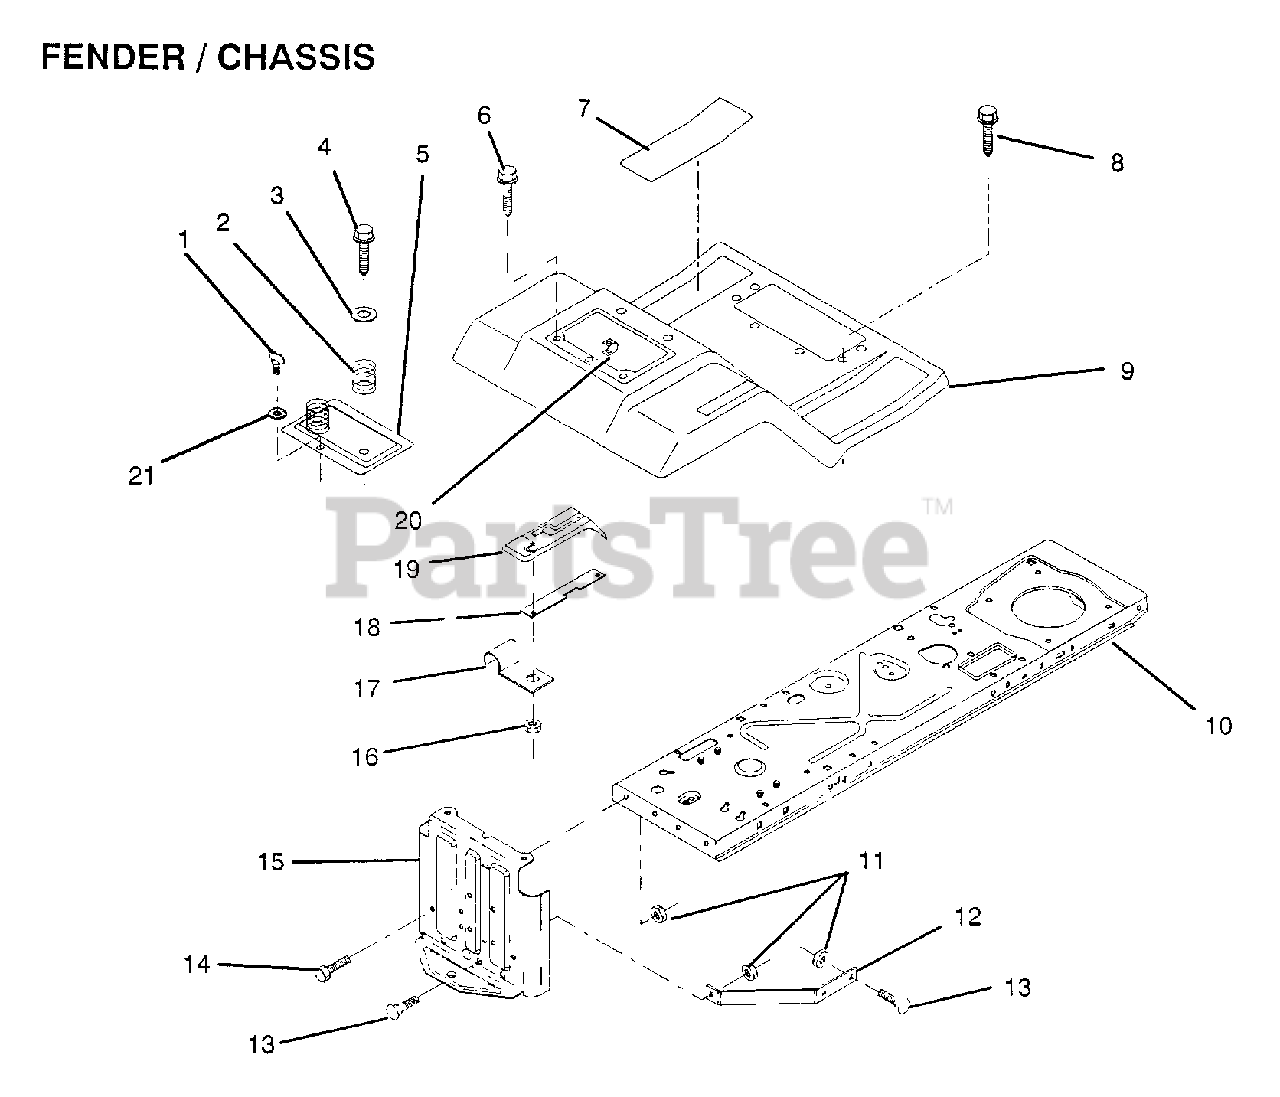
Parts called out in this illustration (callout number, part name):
1	STUD.1/4.TURN
2	SPRING COMPRESSIO
3	WASHER
4	SCREW
6	SCREW LT
7	PAD FOOTREST
8	SCREW
9	FENDER/FOOTREST
10	FRAME ASS'Y
12	"BRACE,DRAWBAR "
13	BOLT
14	BOLT
15	DRAWBAR
16	NUT
17	"CLIP,INSULATOR"
19	"CONSOLE,SHIFT CON"
20	RECEPTACLE LT
21	RETAINER LT
